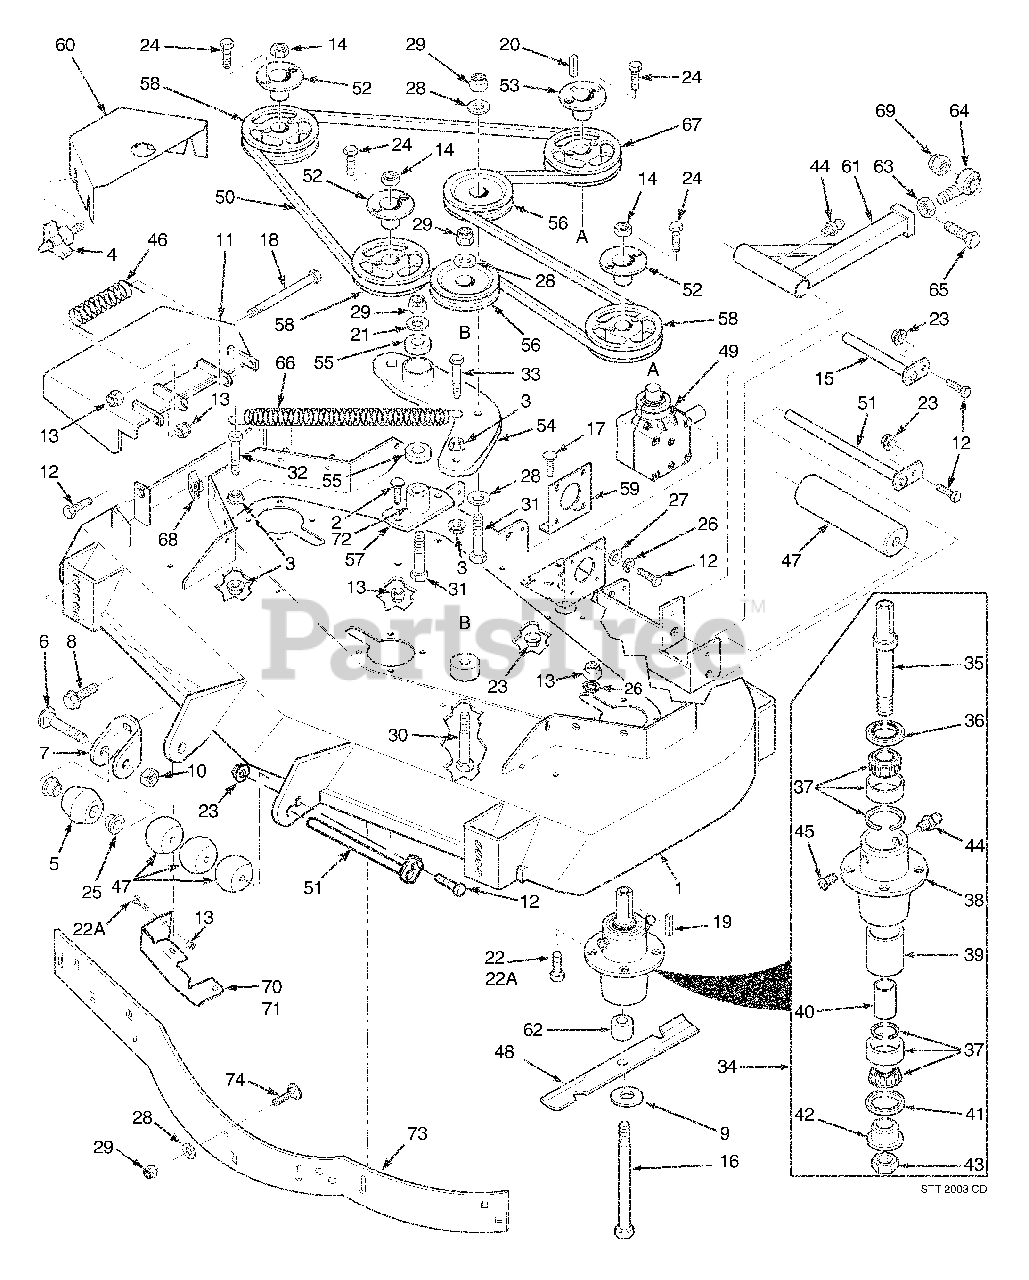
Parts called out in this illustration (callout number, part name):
1	Cutter Deck Advantage
2	Bolt, Carriage 5/16-18 x 1"
3	Nut, Hex Serrated Flange 3/8-16
4	Wing nut, 3/8-16
5	Anti-Scalp Wheel
6	Bolt, Carriage 3/8-16 x 4"
7	Anti-Scalp Wheel Bracket
8	Bolt, Hex Serrated Flange 3/8-16 x 1"
9	Flatwasher, 5/8" Hardened
10	Locknut, 3/8-16 Center Lock
11	Discharge Chute Advantage - Large
12	Bolt, Hex Head 5/16-18 x 1-3/4" - Front
13	Nut, Hex Elastic Stop 5/16-18
14	Nut, 5/8-11 UNC
16	Bolt, Hex Head 5/8-11 x 9-1/2"
17	Bolt, Carriage 5/16-18 x 3/4"
18	Bolt, Hex Head 5/16-18 x 4-1/2"
19	Key, 1/4 x 1/4 x 2"
20	Key, 1/4 x 1/4 x 1-1/4"
21	Flatwasher,3/8-.39 x .938 x .105 HD
22	Bolt, Hex Head 5/16-18 x 1-1/4"
22A	Bolt, Hex Head 5/16-18 x 1-1/2"
23	Nut, Hex Serrated Flange 5/16-18
24	Bolt, Hex Head 1/2-20 x 3/4"
25	Bushing, .376 I.D. Oilite
26	Lockwasher, 5/16"
27	Flatwasher, 5/16" (.375 x .875 x .083)
28	Flatwasher, 3/8" (.391 x .938 x .105)
29	Nut, Hex Elastic Stop 3/8-16
30	Bolt, Hex Head 3/8-16 x 3-1/4"
31	Bolt, Hex Head 3/8-16 x 2-1/2"
32	Bolt, Hex Head 3/8-16 x 1-1/2"
33	Bolt, Hex Head 3/8-16 x 1-1/2" Grade 8
34	Spindle Assembly
35	Spindle Shaft
36	Seal, Top
37	Bearing Assembly
38	Spindle Housing
39	Spacer, Outside
40	Spacer, Inside
41	Seal, Bottom
42	Spindle Bushing, Bottom
43	Nut, Special 1 - 1/16-18
44	Grease Fitting
45	Relief Fitting, Tapered Spindle
46	Spring, Discharge Chute
47	Wheel, Anti-Scalp
48	Cutter Blade, 21"
49	Gearbox Assembly, Deck Drive
50	Belt, Cutter Deck Drive
51	Roller Shaft
52	Tapered Hub, 1-1/8" Bore
53	Tapered Hub, 1" Bore
54	Idler Arm, Cutter Deck
55	Bearings, Ball
56	Pulley, Idler
57	Base, Idler Pivot
58	Pulley, 6.75 O.D. 61")
59	Mounting Plate, Gearbox
60	Belt, Cover
61	Pusharm
62	Spacer, Spindle Bottom
63	Nut, Hex Head 5/8-18 UNF
64	Rod End, 5/8" Male RH Thread
65	Bolt, Hex Head 5/8-11 x 4-1/2"
66	Spring, Cutter Deck
67	Pulley, 6.75 O.D.
68	U-Nut, 3/8-16
69	Nut, Hex Elastic Stop 5/8-11
71	Discharge Baffle 61"
72	Pivot, Idler - Short
73	Baffle, Custom Cut 61A
74	Bolt, Carriage 3/8-16 x 1"
